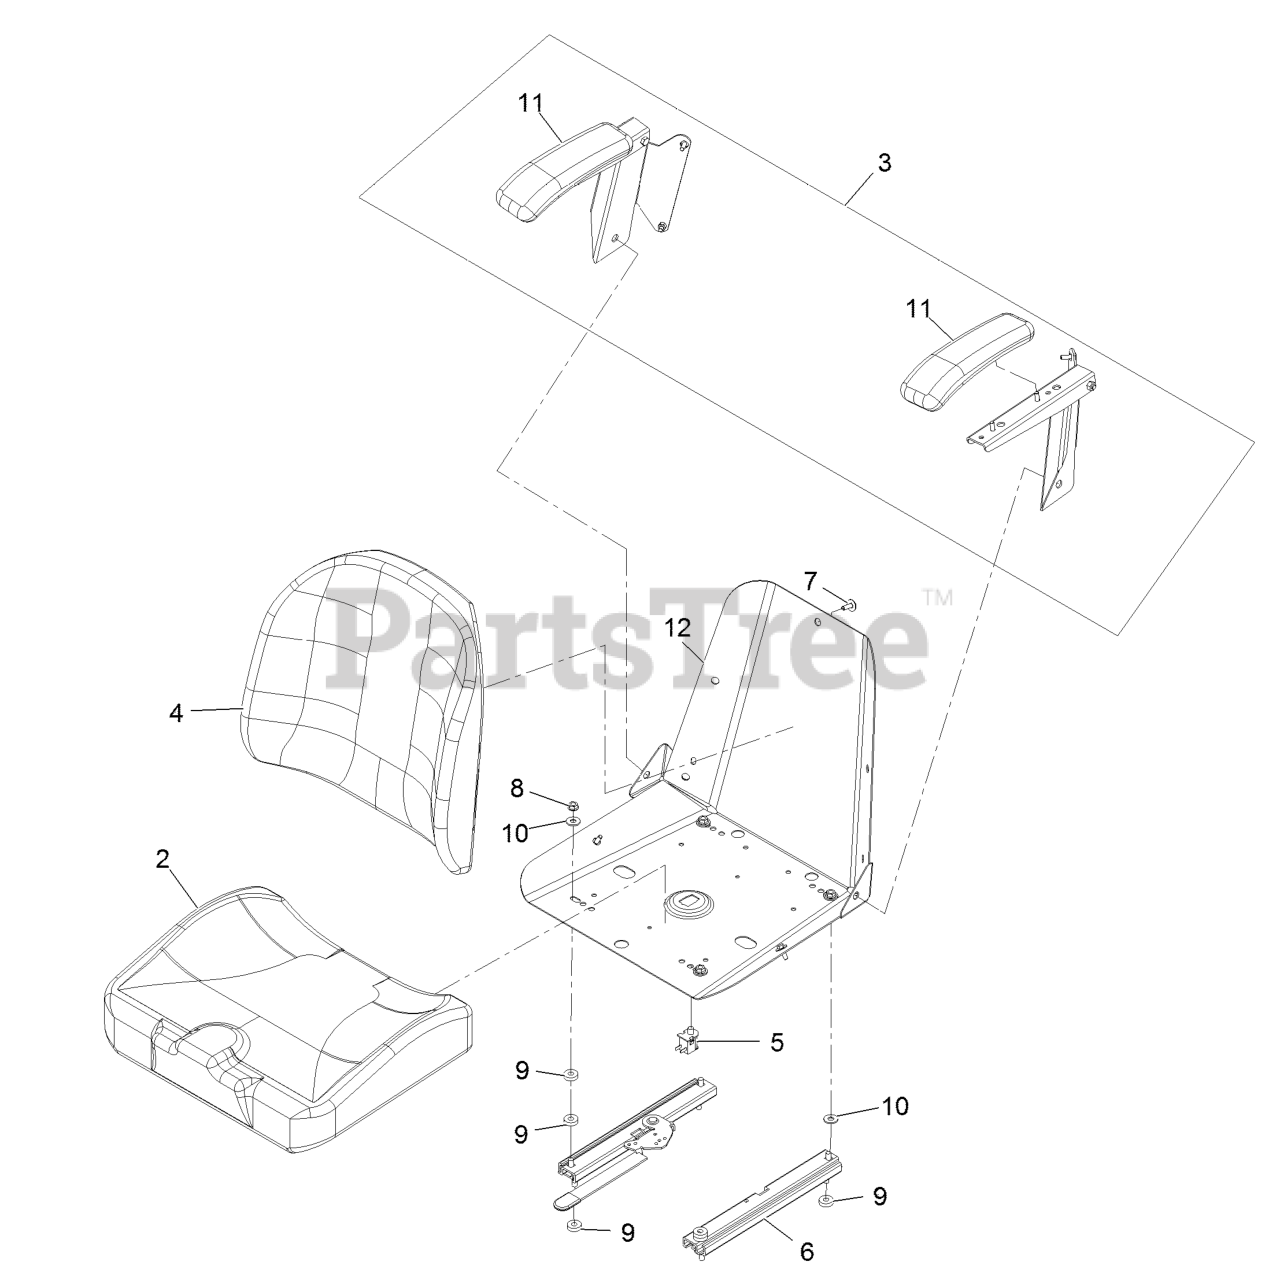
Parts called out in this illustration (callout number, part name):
2	CUSHION-SEAT BOTTOM
3	ARMREST KIT
4	CUSHION,SEAT BACK
5	SWITCH-BAIL
6	TRACK-SEAT
7	BOLT-SEAT
10	WASHER-FLAT
11	CUSHION-REST, ARM
12	FRAME-SEAT
